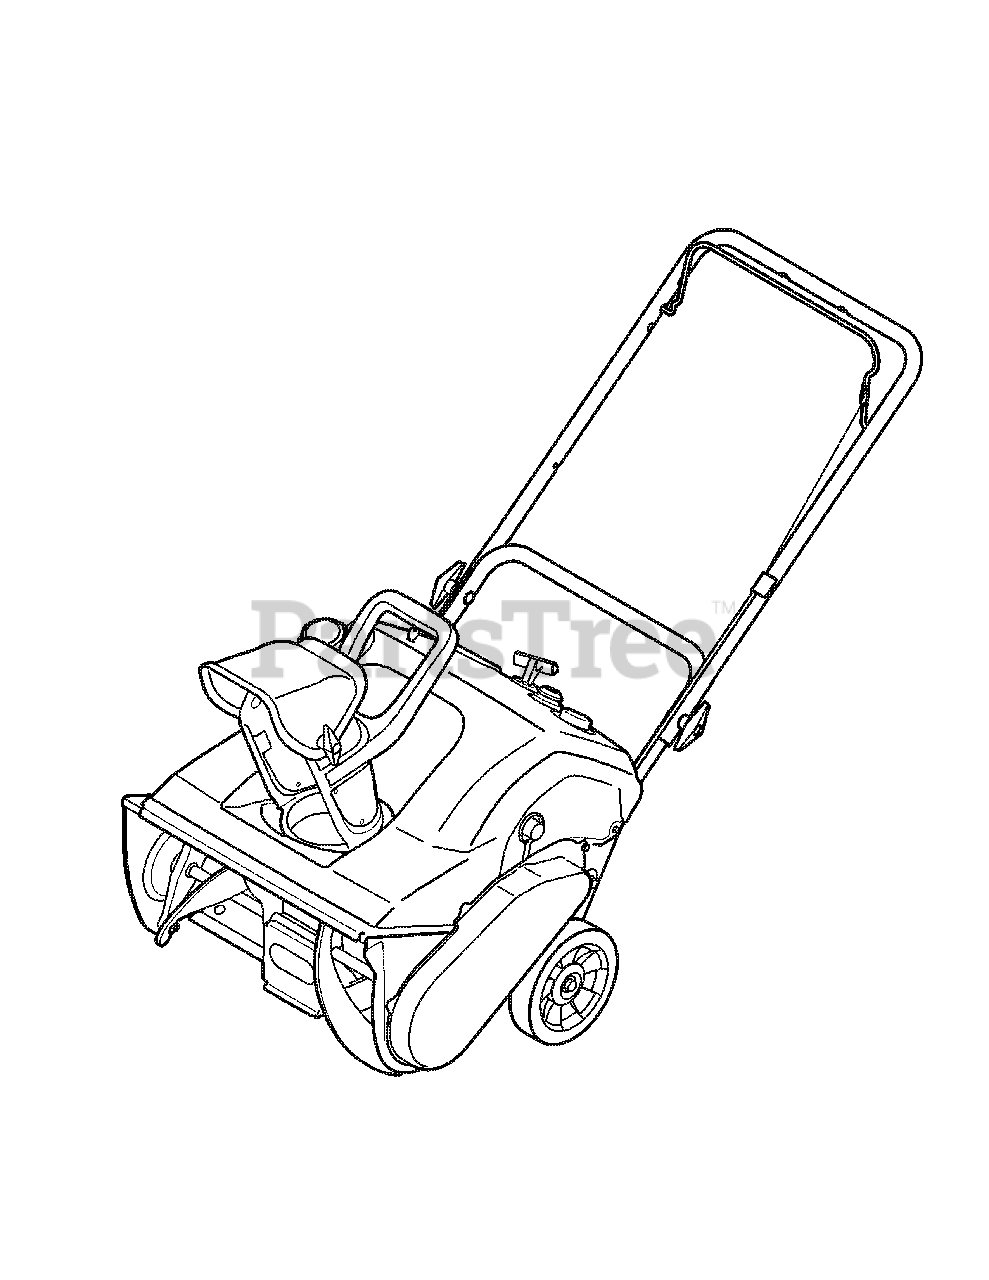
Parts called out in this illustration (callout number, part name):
NA	Snow Removal Tool
NA	Slide Shoe
NA	Shear Pin
NA	Bow Tie Cotter Pin
NA	Lamp
NA	Wheel Drive Belt
NA	Friction Wheel Assembly
NA	Friction Wheel Rubber
